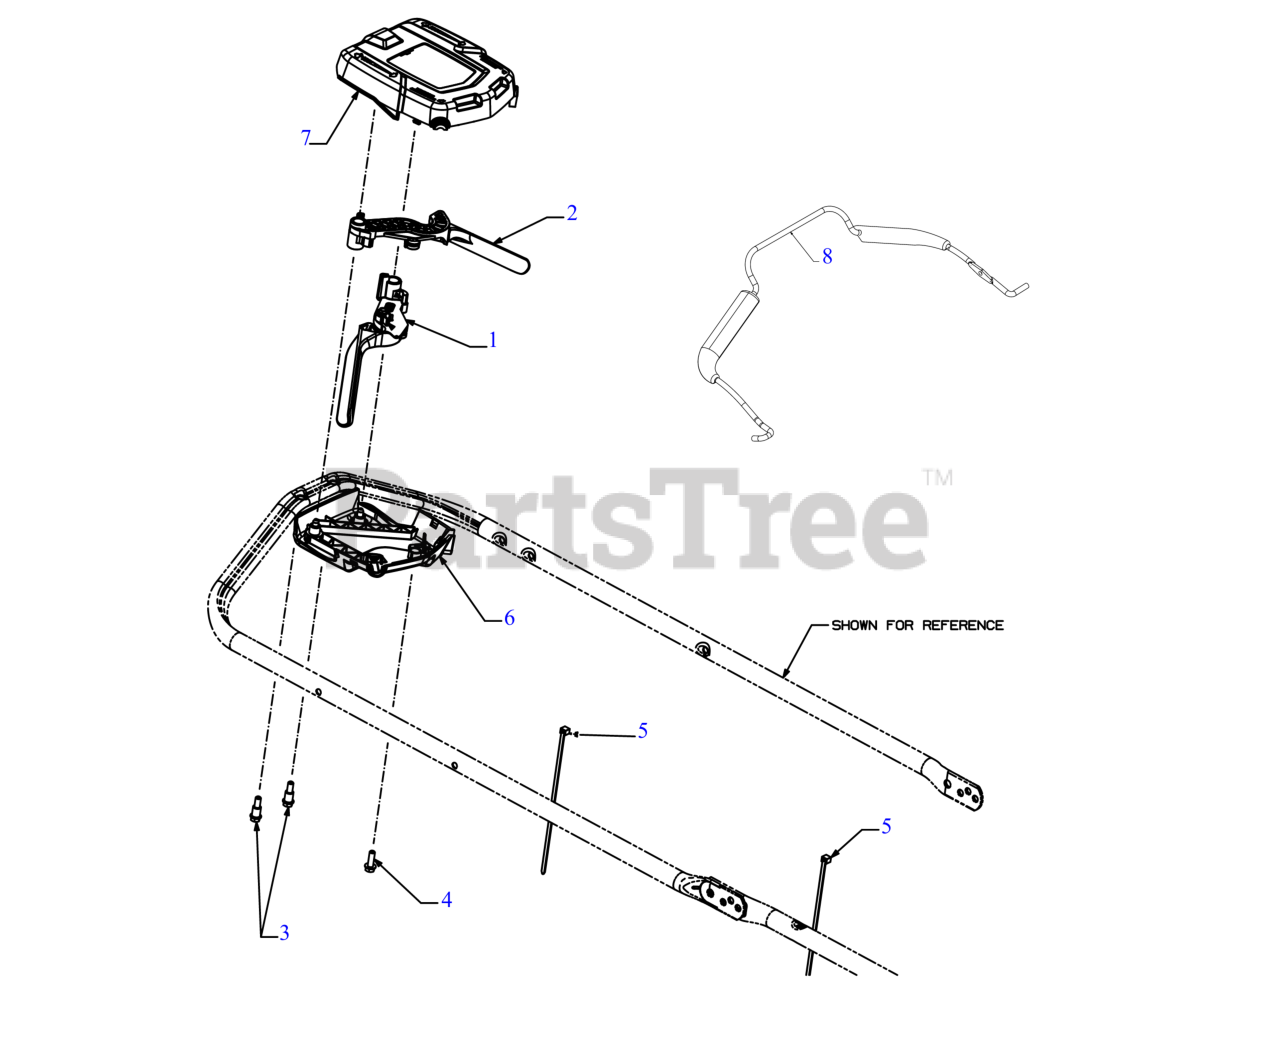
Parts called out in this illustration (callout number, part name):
1	CONTROL LEVER (ERGO AWD) (RH)
2	CONTROL LEVER (ERGO AWD) (LH)
3	SHOULDER SCREW 1/4-15 x .970
4	SCREW 1/4-15 x .750
5	7" CABLE TIE
6	LOWER CONTROL HOUSING
7	UPPER CONTROL HOUSING
8	OPERATOR BAIL (AWD) (LIBERTY RED)
